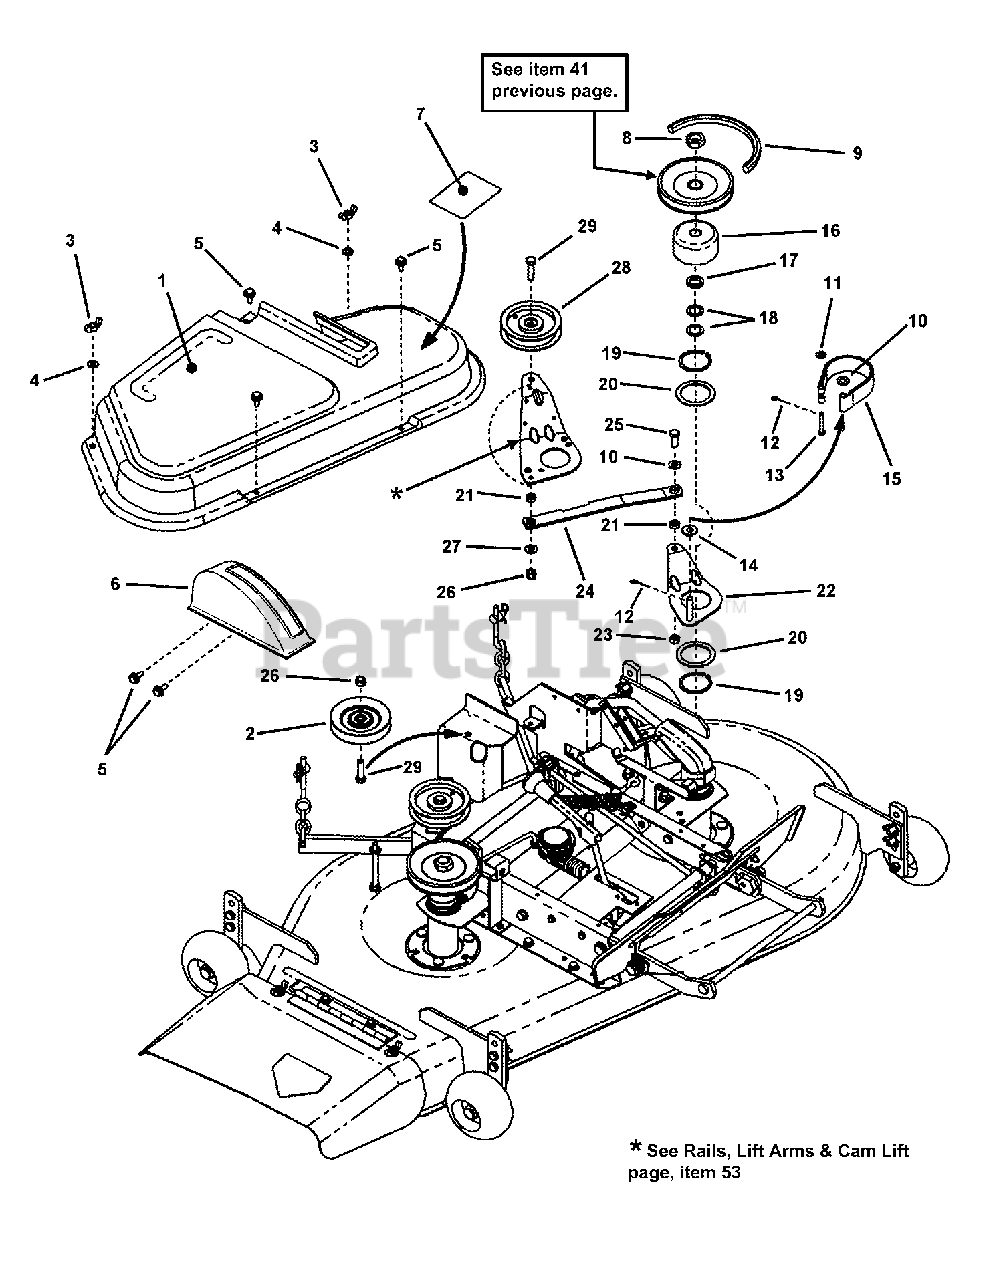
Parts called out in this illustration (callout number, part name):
1	COVER, Belt, 42" RER
2	PULLEY, Seam Welded Idler
3	WING-NUT, 5/16-18
4	WASHER, 5/16" Flat
5	SCREW, 1/4-20 x 5/8" Hex Head w/Free Spinning Washer
6	COVER, Lift Quadrant
7	DECAL, Brake/Blade Operation
8	NUT, 3/4-16 Hex Jam, GR 8
9	BELT, 5L Section (110.28" effective length)
10	WASHER, 3/8" Flat SAE
11	WASHER, 1/4" Flat
12	PIN, 3/32 x 3/4" Cotter
13	PIN, 1/4 x 1-5/8" Clevis
14	SPACER, .39 x 1.0 x .31 Nylon
15	BAND, Brake (Formed)
16	DRUM, Brake Spindle
18	WASHER, .77 x 1.13 x .06 Flat
19	RING, 2" External Retaining
20	WASHER, Nylon
21	SPACER
22	WELDMENT, Brake Arm
23	NUT, 3/8-24 Hex Center Lock
25	SCREW, 3/8-24 x 1" Hex Head Cap, GR5
26	NUT, 3/8-16 Hex Nyloc
27	WASHER, 3/8" Flat
28	IDLER, 4-1/8" Flat
29	SCREW, 3/8-16 x 1-1/2" Hex Head Cap, GR5
